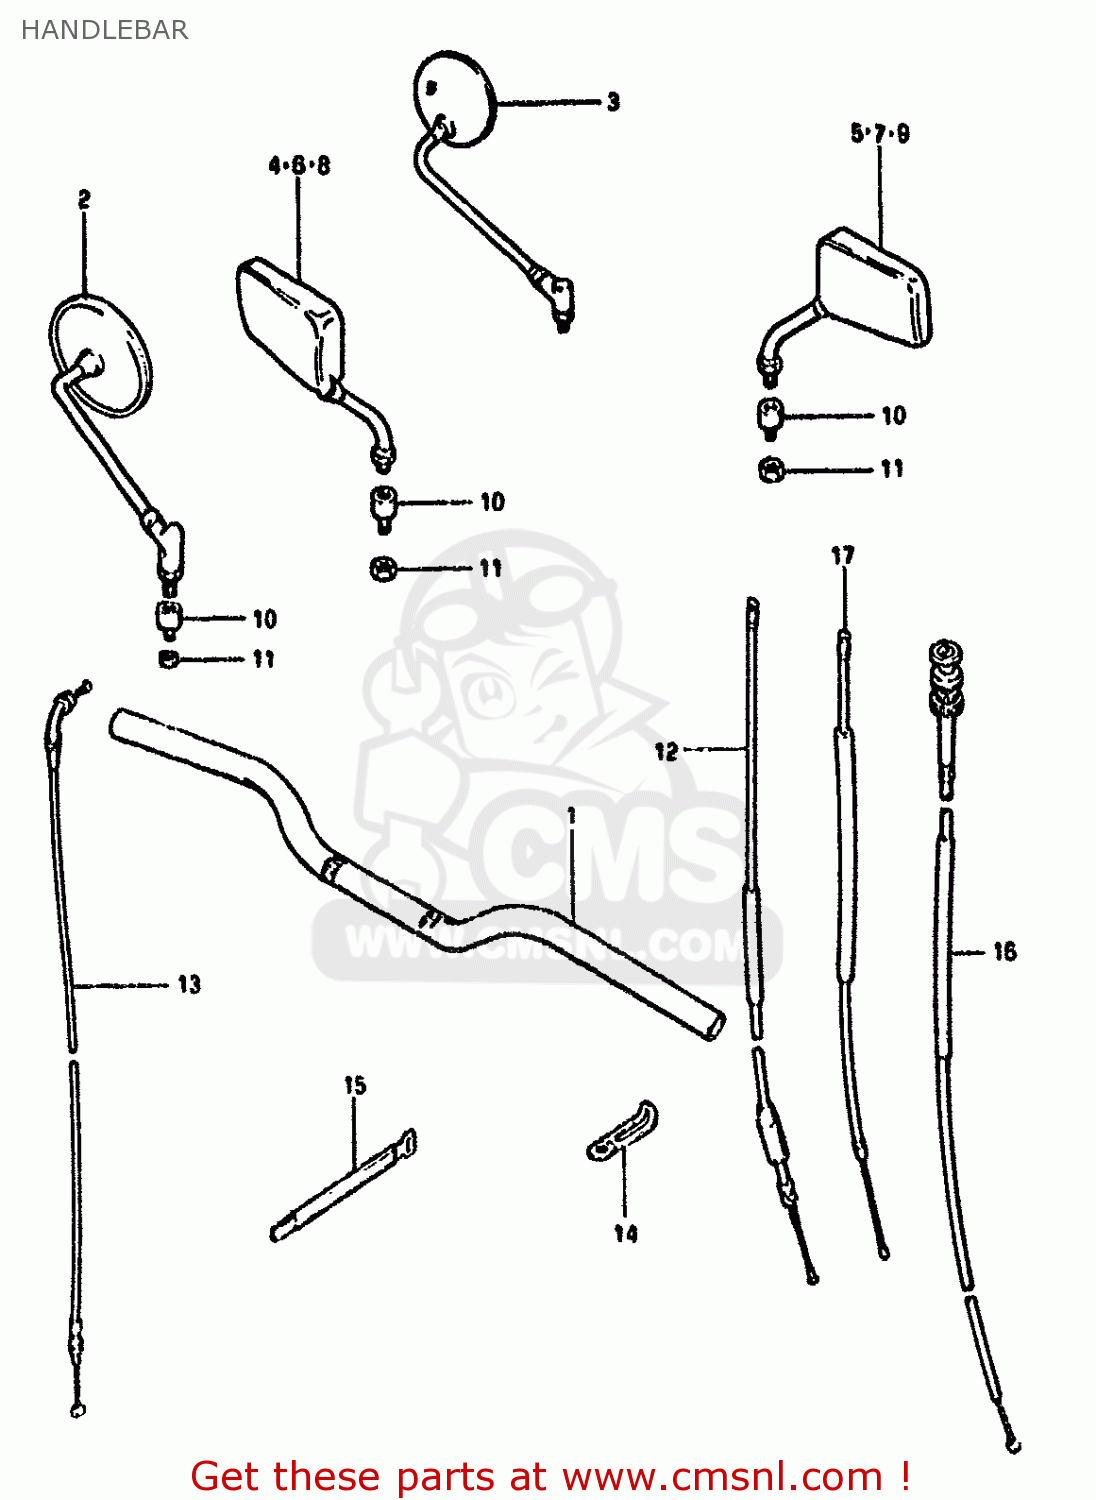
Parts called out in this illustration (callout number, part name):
1	HANDLEBAR
2	MIRROR ASSY,RH
3	MIRROR ASSY,RH
4	MIRROR, REAR VIEW RH
5	MIRROR, REAR VIEW LH
6	MIRROR, REAR VIEW RH
7	MIRROR, REAR VIEW LH
8	MIRROR ASSEMBLY,REAR VIEW
9	MIRROR ASSEMBLY,REAR VIEW
10	CUSHION,REAR VIEW MIRROR
11	NUT
12	CABLE, CLUTCH (FLAT)
13	CABLE ASSEMBLY,THROTTLE
14	CLAMP
15	CLAMP
16	CABLE ASSEMBLY,STARTER
17	CABLE, STARTER
